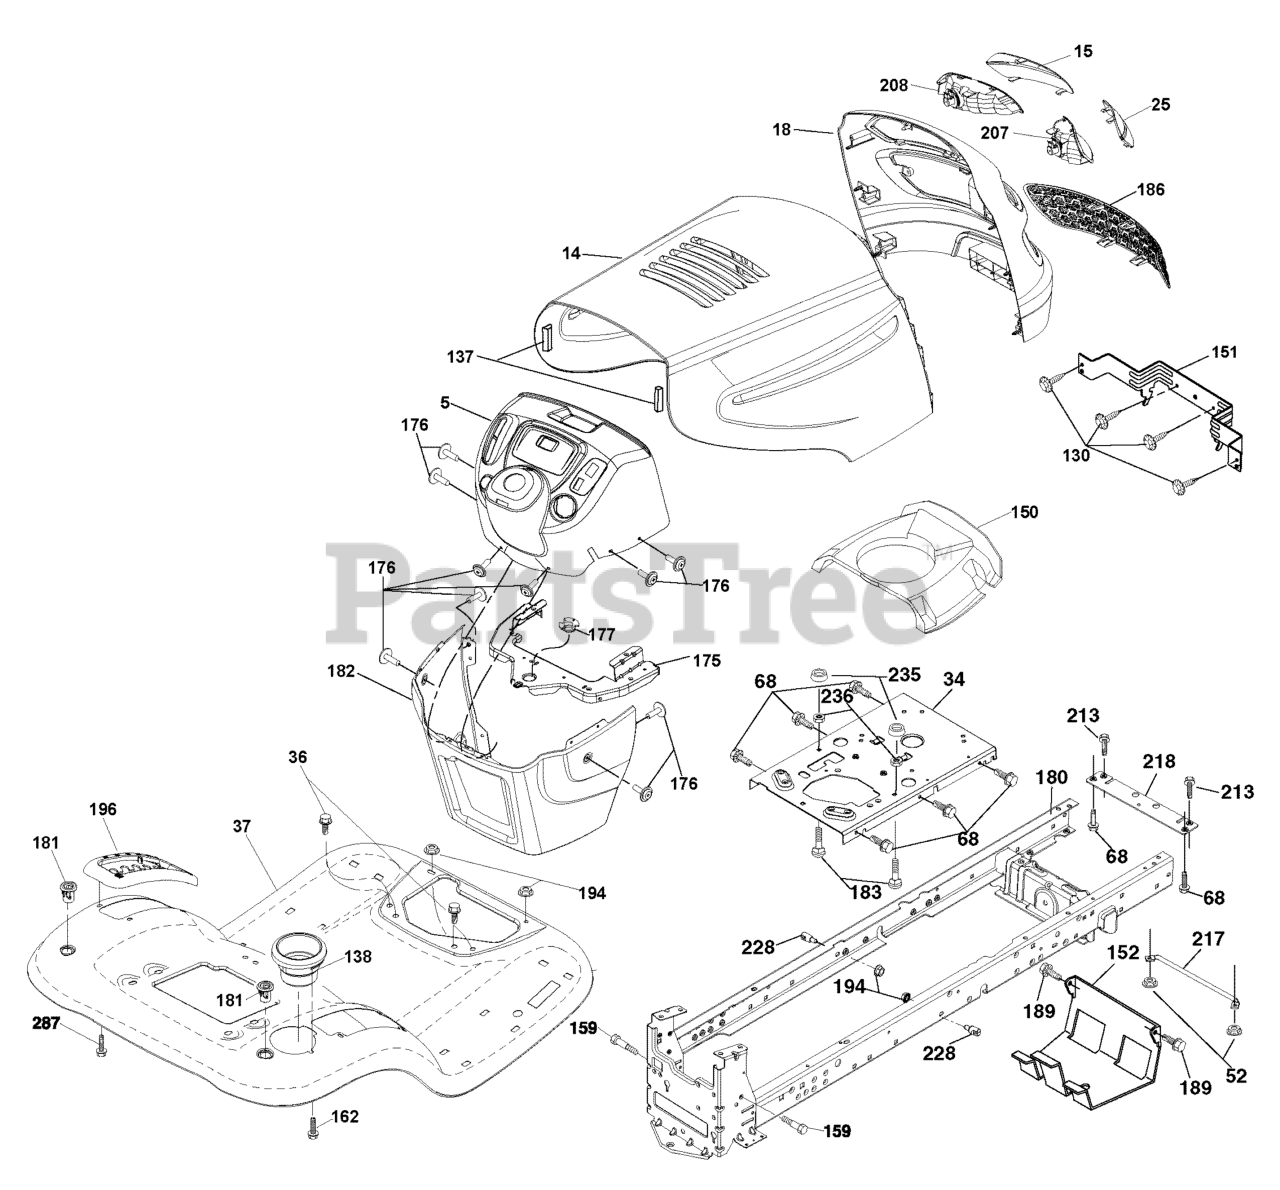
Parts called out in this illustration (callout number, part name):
15	Lens Grille LH
18	Grille
25	Lens Grille RH
34	Plate Engine
36	Screw 5/16-18 x 3/4
37	Fender
52	Nut Crown Lock 5/16-18
68	Screw Thdrol 5/16-18 x 1/2
130	Screw #10 x 0.750
137	Bumper Hood
138	Cupholder
150	Duct Heat Hood
151	Bracket Pivot
152	Shield Browning
159	Screw Hexwsh Thdrol 3/8-16 x 3/4
162	Screw Hex Wsh Hi-Lo 1/4 x 1/2
175	Crossmember
176	Screw 10-24 x 5/8 Wshd Qdrx
177	Bushing Steering
180	Chassis
181	Bushing Mtg. Fender Crgo.
182	Dash Lower
183	Bolt Full Thd 5/16-18 x 1-1/4
186	Insert Grille
189	Screw 5/16-18 x 3/4
194	Nut Lock Hex Flange 5/16-18
196	Console Asm. Deck Lift
207	Bezel Grille RH
208	Bezel Grille LH
213	Bolt Hex HD 5/16-18 unc x 3/4
217	Rod Pivot Chassis
218	X-Piece Hood Stop
228	Stud Fastener
235	Spacer Fender
236	Nut Center Lock 5/16-18
287	Screw hex 1/4-20 x 3/8
